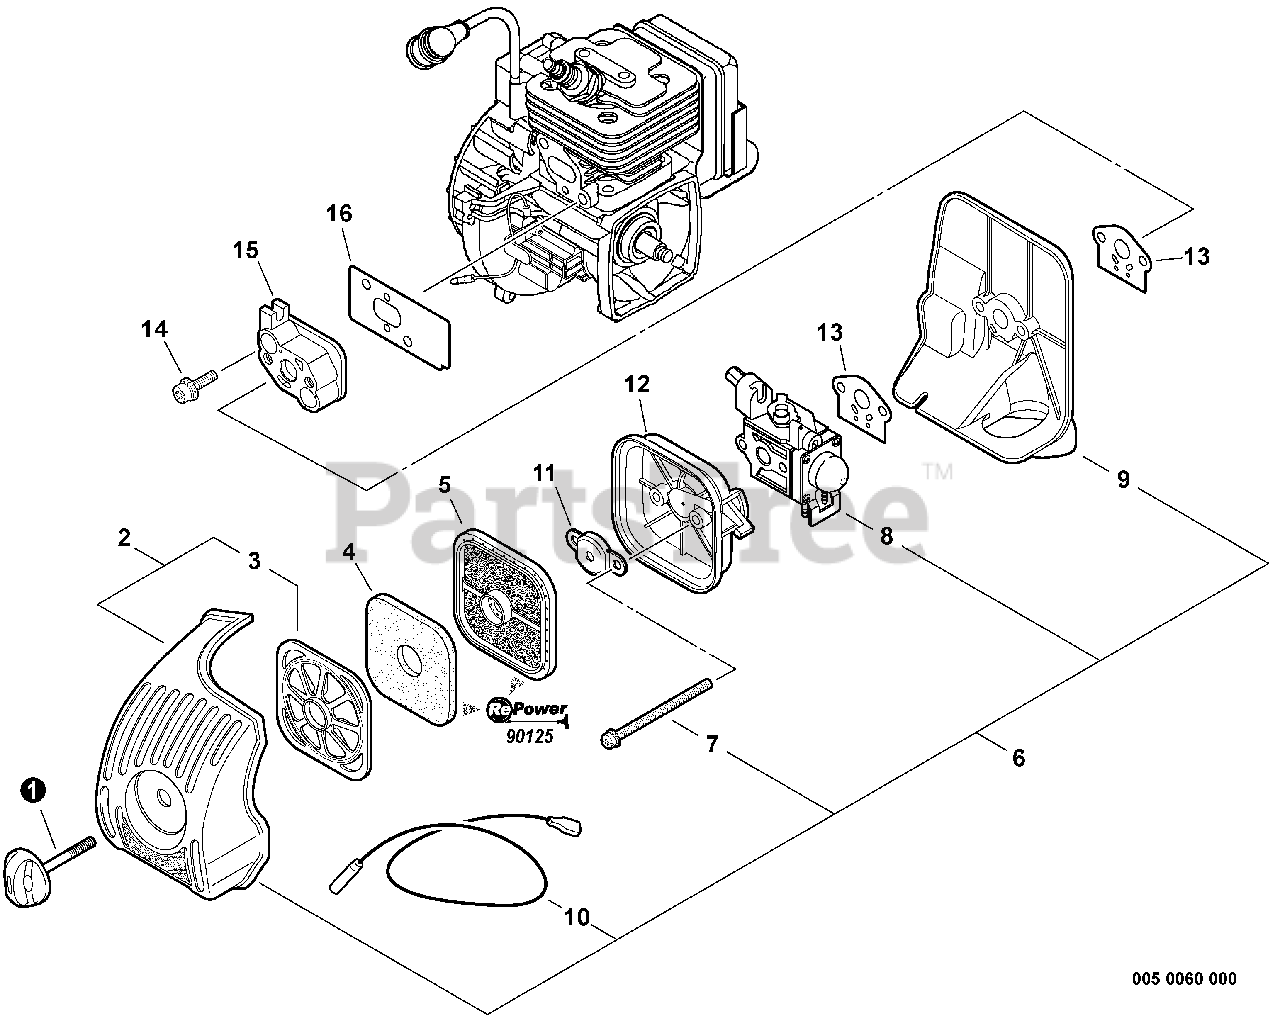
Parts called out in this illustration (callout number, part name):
1	GASKET KIT
2	GASKET, CRANKCASE
3	GASKET, CYLINDER
4	HEAT SHIELD, INTAKE
5	GASKET, INTAKE
6	HEAT SHIELD, EXHAUST
7	GASKET, EXHAUST
8	TUNE-UP KIT - REPOWER
9	PRE-FILTER, FOAM
10	FILTER, AIR - DOUBLE LAYER
11	FILTER, FUEL
12	SPARK PLUG - BPMR8Y
13	FUEL SYSTEM KIT
14	VENT ASSY
15	CLIP Ø6.5 MM
16	PIPE, FUEL 3×6×35 BLACK
17	PIPE, FUEL 3×5×195 BLACK
18	PIPE, FUEL 3×6×75 CLEAR
19	GROMMET, FUEL
20	CLIP Ø6
21	FILTER, FUEL 125-528
22	FUEL SYSTEM KIT
23	VENT ASSY
24	CLIP Ø6.5 MM
25	PIPE, FUEL 3×6×35 BLACK
26	PIPE, FUEL - 3×5×67 - BLACK
27	PIPE, FUEL 3×6×75 CLEAR
28	GROMMET, FUEL
29	CONNECTOR, PIPE Ø5ר3.5
30	CLIP Ø6
31	PIPE, FUEL - 3×5×125 - BLACK
32	FILTER, FUEL 125-528
33	GASKET, FUEL CAP
34	CAP/VENT KIT - REPOWER
35	CAP, FUEL
36	VENT ASSY
37	GASKET, FUEL CAP
38	BULK PIPE - 3×5 MM BLACK (4 PIECES×2 M)
39	BULK PIPE - 3×6 MM CLEAR (4 PIECES×2 M)
40	BULK PIPE - 3×6 MM BLACK (4 PIECES×2 M)
41	BULK STARTER ROPE - Ø 3.0 MM×61 M
